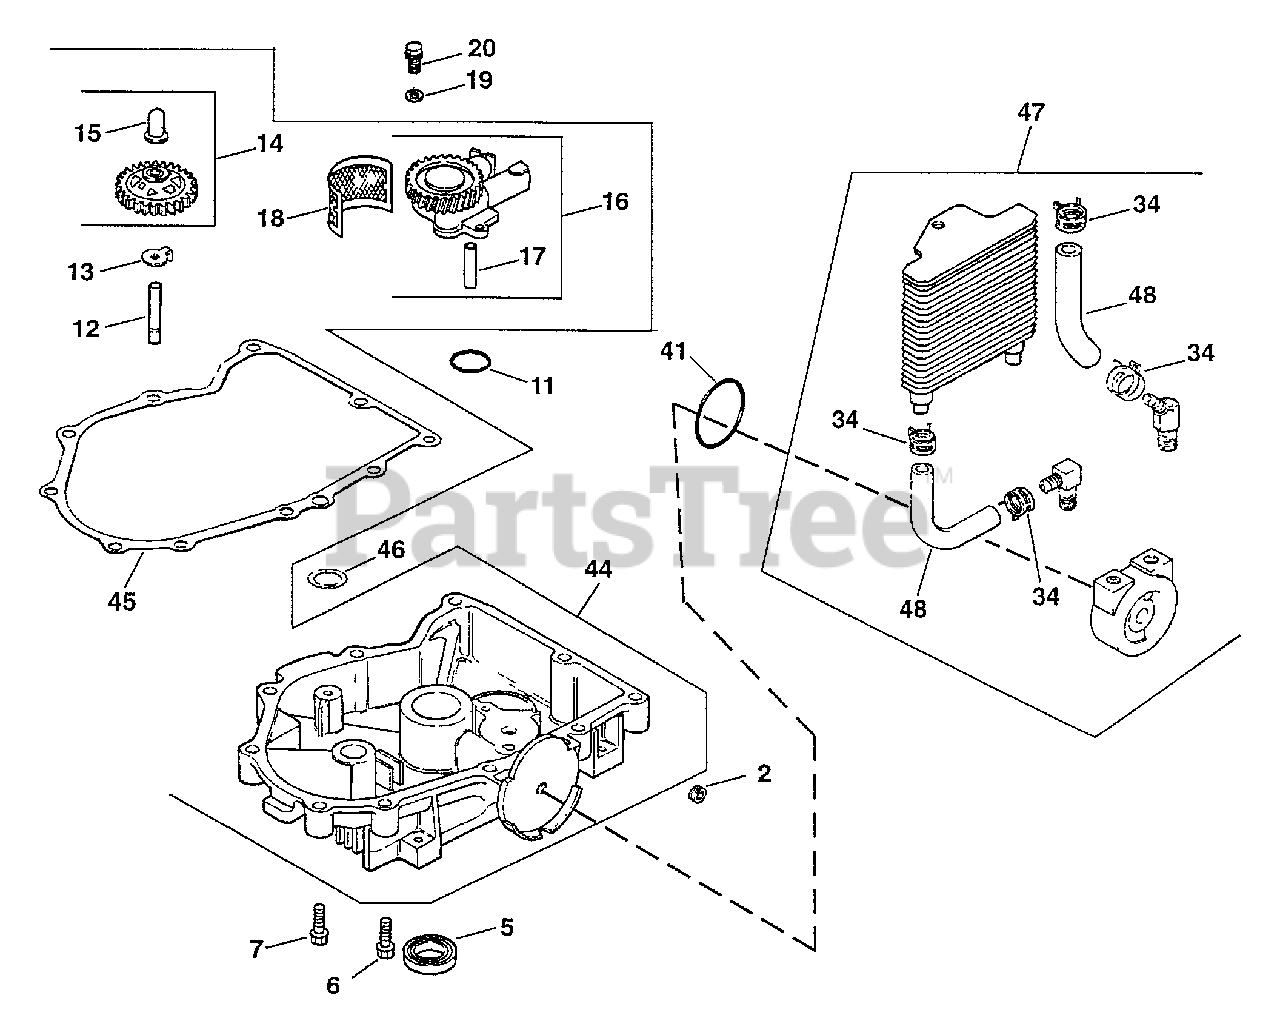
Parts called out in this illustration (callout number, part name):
2	PLUG, PIPE CTSK 3/8" USE 25 139 62-S
5	SEAL, OIL (KM)-USE 25 032 06-S
6	SCREW, FLG M8X1.25X45
7	SCREW, HEX FLANGE -USE 24 086 17-S
12	SHAFT, GOVERNOR GEAR
14	KIT, GOVERNOR GEAR W/PIN
15	PIN, GOVERNOR REGULATING
18	SCREEN, OIL-USE 24 162 26-S
19	WASHER - USE M-631005
20	SCREW - USE M-645025
44	OIL PAN W/GASKET KIT-USE 24 755 128-S
46	SHIM, THRUST (GREEN .875MM) - DISCONTINUED
48	HOSE-USE 24 326 17-S
